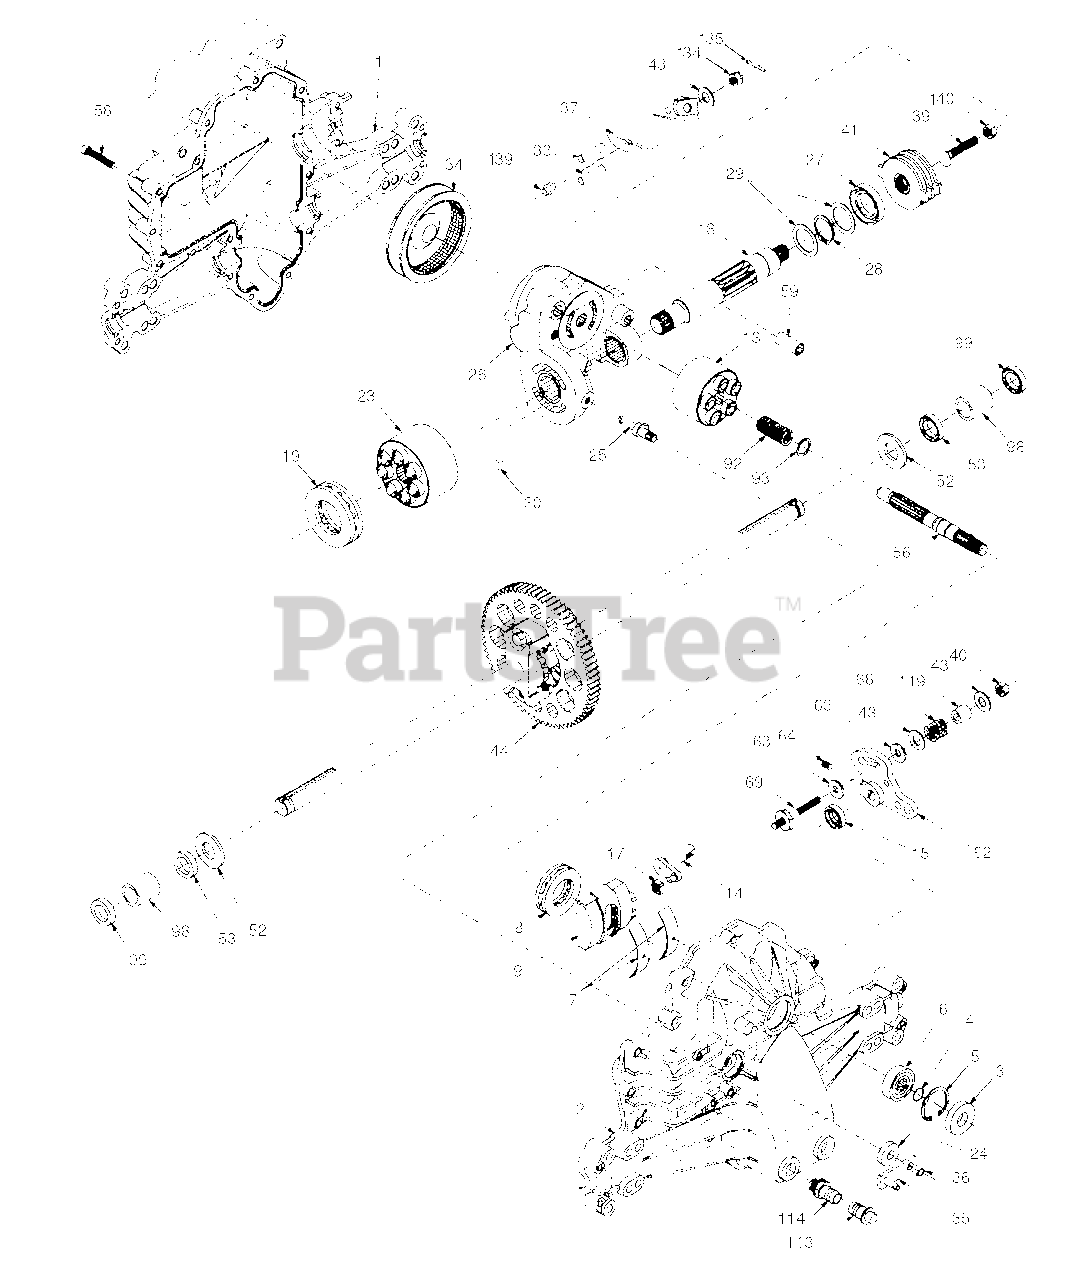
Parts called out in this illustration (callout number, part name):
1	Housing, Lower
2	Assembly, Upper Housing
4	Ring, Wire Retaining
5	Ring, Retaining
6	Bearing, Shaft Ball
7	Bearing, Cradle
8	Bearing, Thrust 30 x 52 x 13
9	Swashplate, Variable
13	Block, Cylinder Assembly
14	Arm, Trunnion
17	Guide, Slot
18	Shaft, Motor
19	Bearing, Thrust 42 x 68 x 16
23	Block, Cylinder Assembly
24	Seal, Lip 10 x 25 x 7
25	Actuator, Bypass
26	Center Section Assembly Kit
27	Seal, Lip 26 x 42 x 8
28	Ring, Retaining
29	Washer 26 x 35 x 1
34	Oil Filter Element
35	Arm, Bypass
36	Ring, Retaining
37	Arm, Actuating
38	Pin, Actuating
39	Bolt 5/16-24 x 1-3/4
40	Locknut, Hex 5/16-24 UNJC
41	Brake Rotor/Stator Kit
43	Washer 7/16 x 7/8 x .060
44	Differential Assembly
52	Washer 3/4 x 1.5 x .13
53	Seal .75 x 1.25 x .250
56	Shaft, Input
58	Bolt 1/4-20 x 1.38
59	Pin .5 OD x .43 ID x .750
62	Arm, Control
63	Puck, Dampener
69	Stud 5/16-24
92	Spring, Block
93	Washer, Block Thrust
98	Sleeve Bearing
99	Seal, Wiper
113	Cap, Vent Assembly
114	Fitting, O-Ring Assembly
119	Spacer
134	Nut, Castle 5/16-24
135	Pin, Cotter
139	Spring, Compression
140	Nut, Hex 5/16-24
